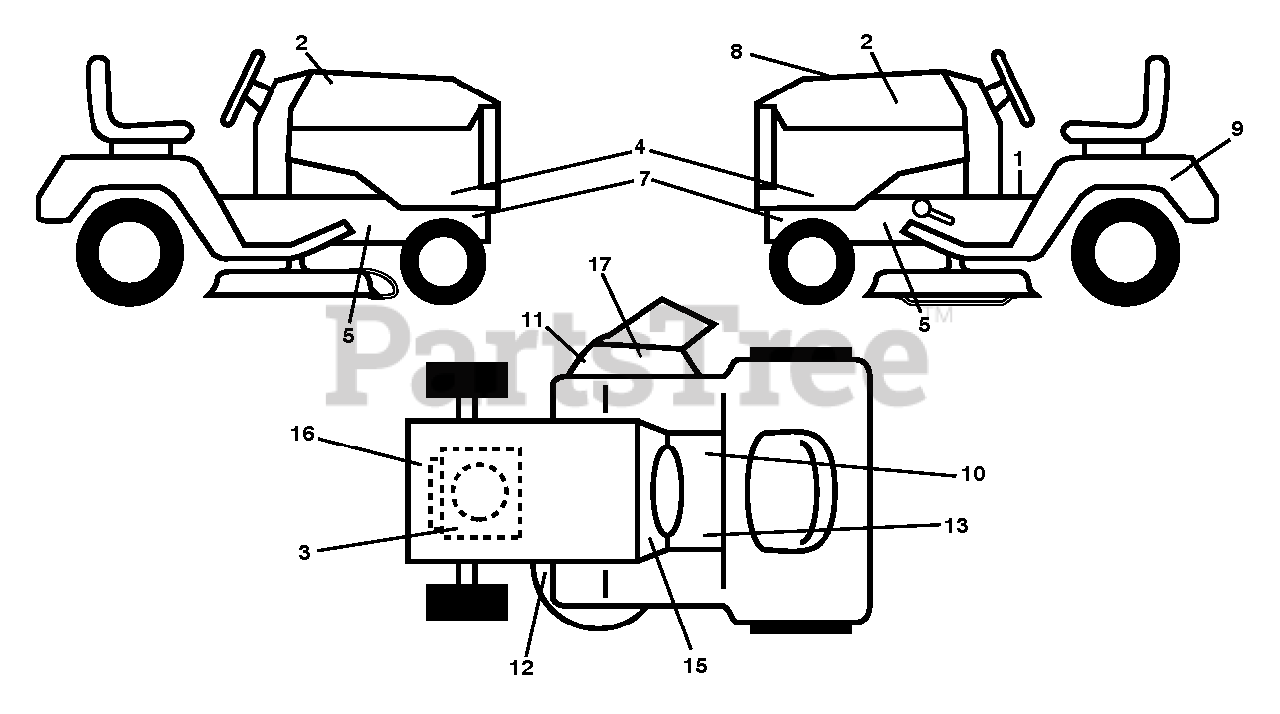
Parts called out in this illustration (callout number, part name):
1	DECAL.READ.OWN.MAN.SYMBOL.LT
2	DECAL.BADGE.170MM.TEXTLOGO.
3	DECAL.ENGINE.WARNING
4	DECAL.SDPNL.HUSQLT.TS142.HUSQV
5	DECAL.CHASSIS.HOT.MUFFLER
7	DECAL.WARNING.SERVCE/FIRE
8	DECAL DECAL.RPL.BSM31.INTK.TLW
9	DECAL BTRY SYMBOLS
10	DECAL.PARKING.BRAKE.SADDLE.LT
11	DECAL.DFLCTR.WARNNG.CTFNGR.SYM
12	DECAL.V-BELT.SCH.42/46"MEC/ELE
13	DECAL.FNDR.SDLE.BRAKE.CLUTCH.6
15	DECAL.SNOWFLAKE.MS498.HUSQ
16	DECAL.ENG.B&S.HS.500CC.382338
17	DECAL, DECK DEFLECTOR, WARNING
